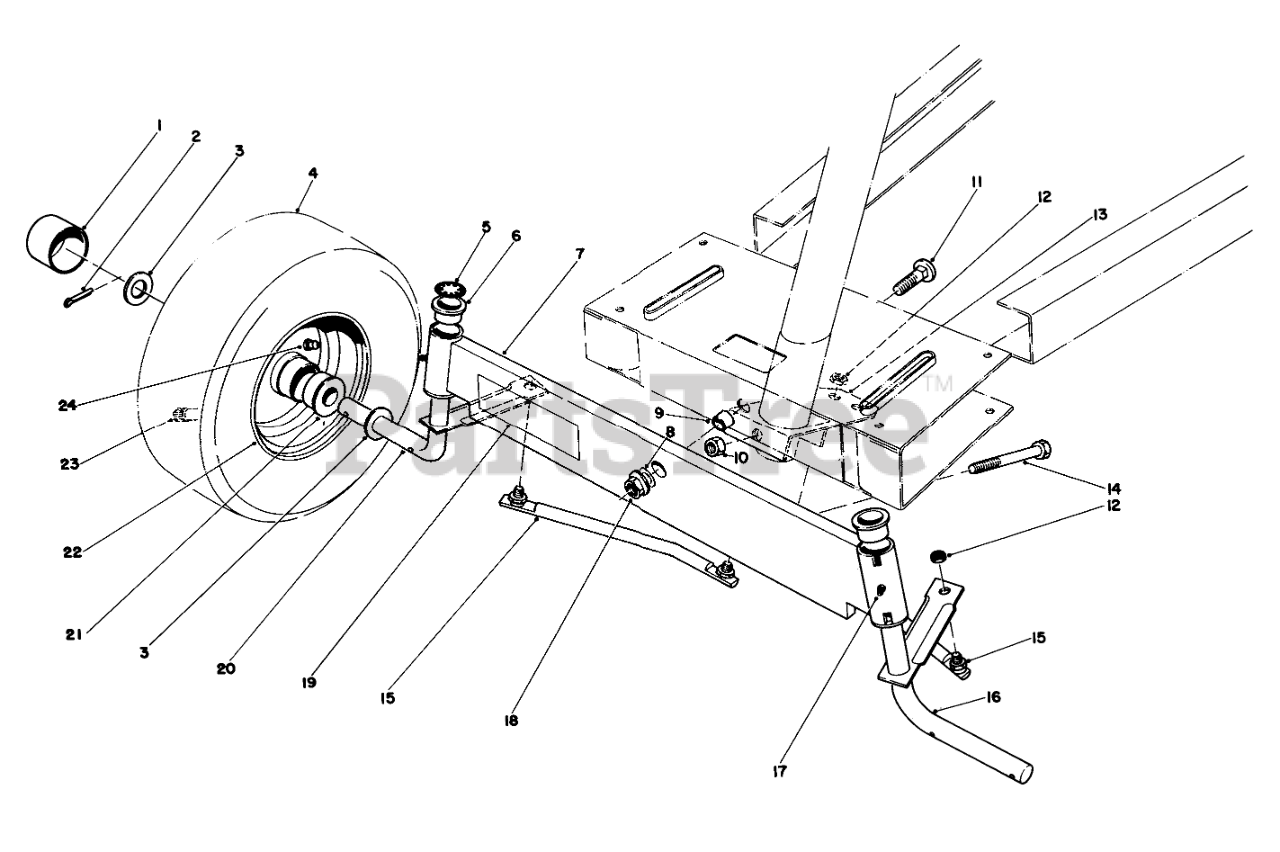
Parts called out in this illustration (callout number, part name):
1	Hub Cap
2	PIN-COTTER
3	WASHER-FLAT
4	Tire
5	Retaining Ring
6	BUSHING
7	Front Axle
8	WASHER-THRUST
9	FRONT AXLE SPACER
10	NUT-LOCK, NI
11	SCREW-CARR
12	NUT-LOCK, NI
13	Lever Steering
14	SCREW-HH
15	TIE ROD ASM
16	Spindle L.H.
17	GREASE FITTING
18	NUT-HF
19	Decal-Instruction
20	SPINDLE WA RH
21	BUSHING
23	STEM-VALVE
24	FITTING-GREASE
